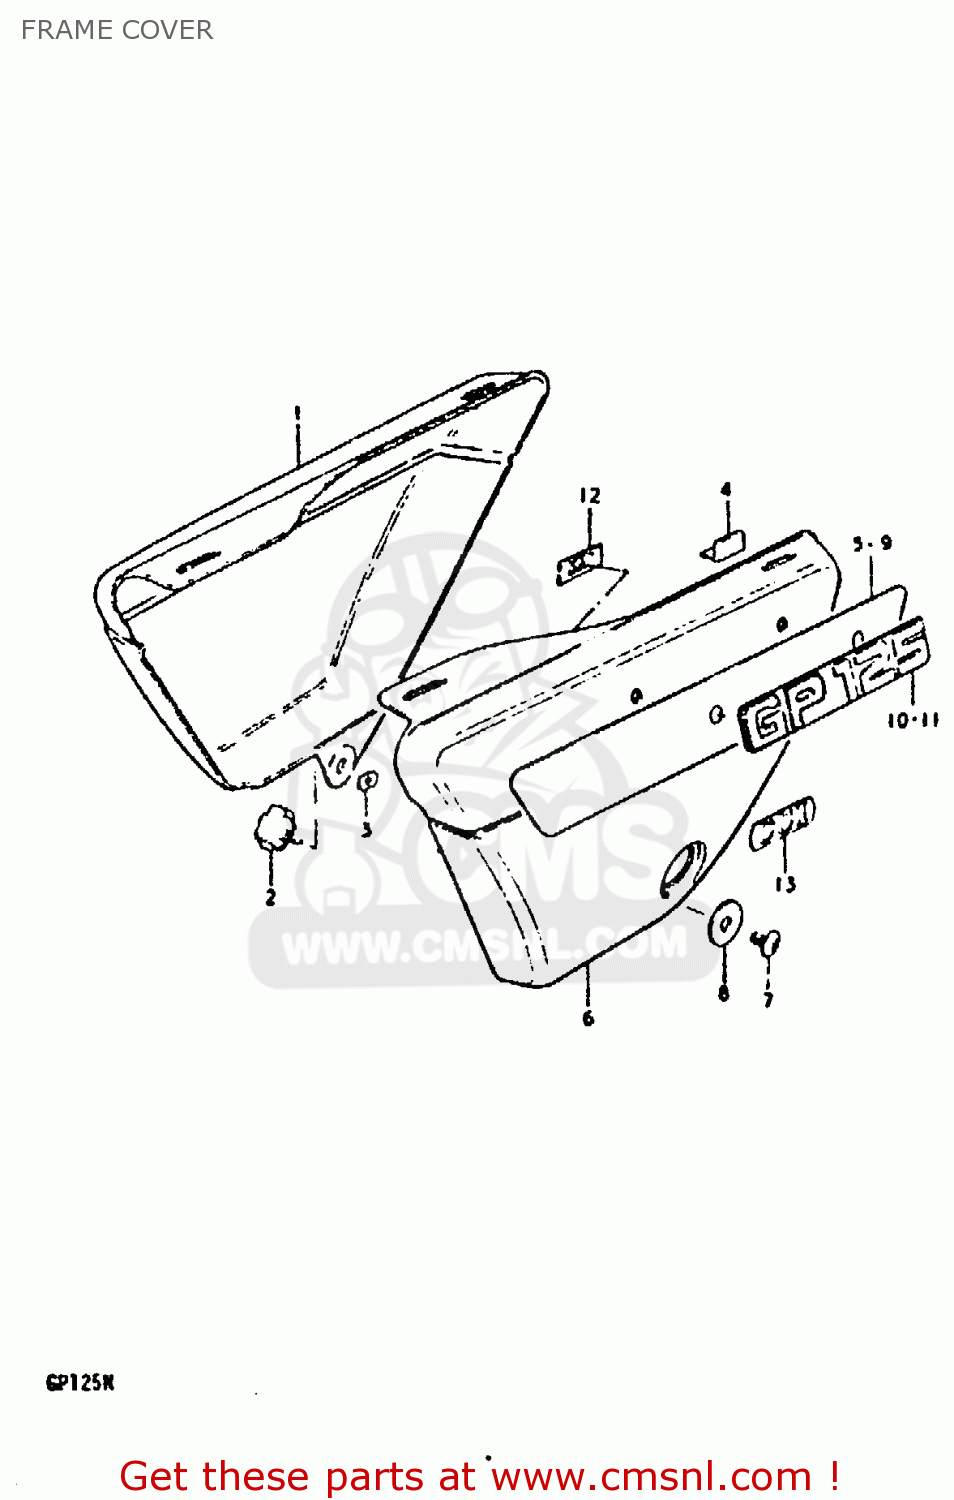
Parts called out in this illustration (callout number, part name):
1	COVER, FRAME RH
2	KNOB,FRAME COVER,R
3	STOPPER
4	CUSHION,FRAME COVER
6	COVER, FRAME LH
7	SCREW
8	WASHER
10	EMBLEM
12	NUT
13	EMBLEM,CCIS
